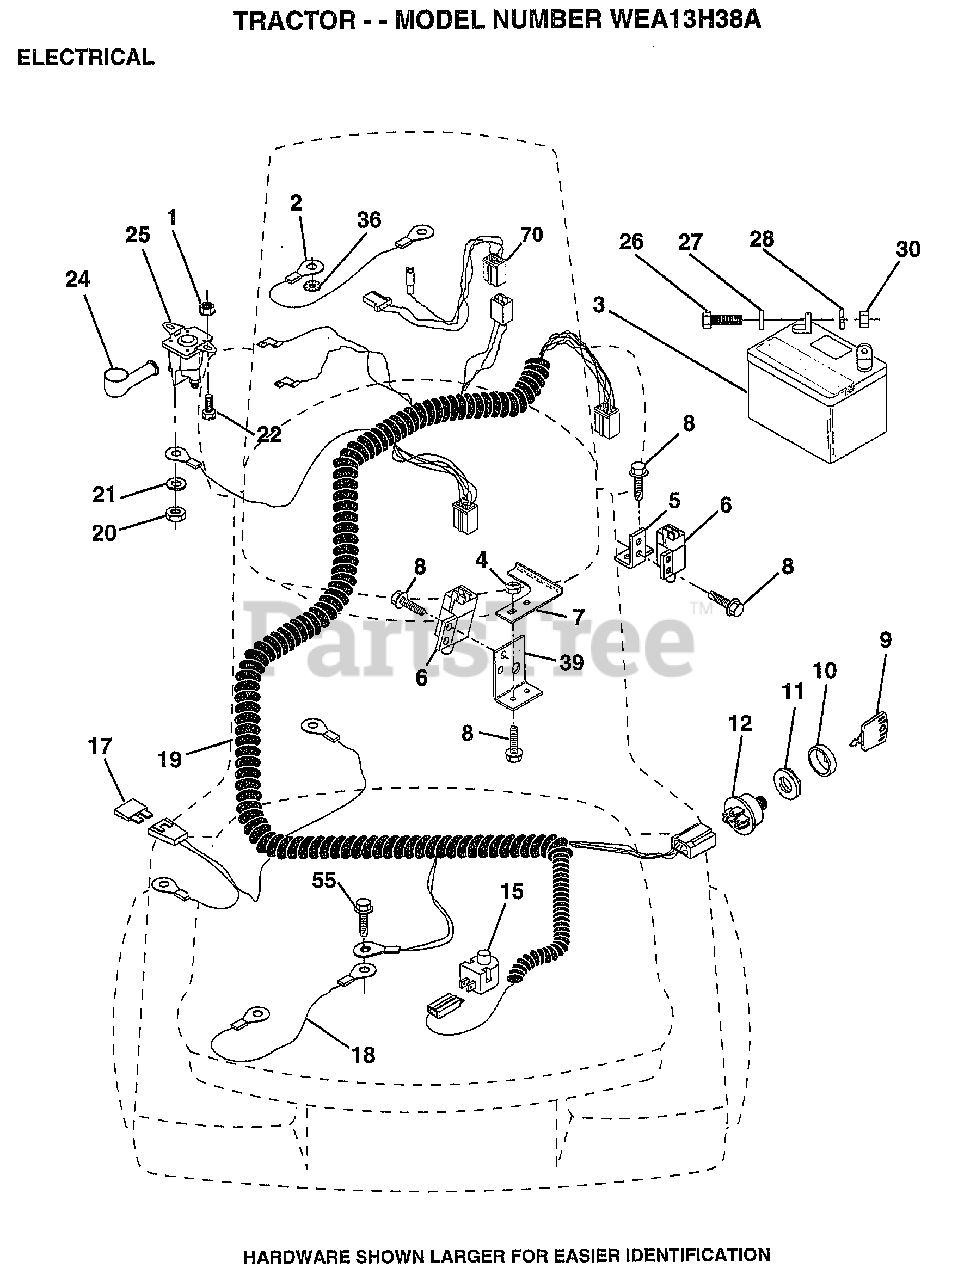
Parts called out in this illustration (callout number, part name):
1	NUT HXKEP 1/4X20
4	LOCKNUT
5	BRACKET LT
6	SWITCH INTERLOCKT
7	KEEPER.ACTUAT.LR.
8	SCREW
9	KEY MLD GEN DELTA
10	COVER KEY SWITCH
12	SWITCH.IGNITION
15	SWITCH SEAT
17	FUSE HYT
18	CABLE ASSY
19	HARNESS.IGN.FEND.
20	NUT
22	BOLT HXHD FIN
27	WASHER
28	LOCKWASHER
36	LOCKWASHER
39	BRACKET SWT CLUTC
